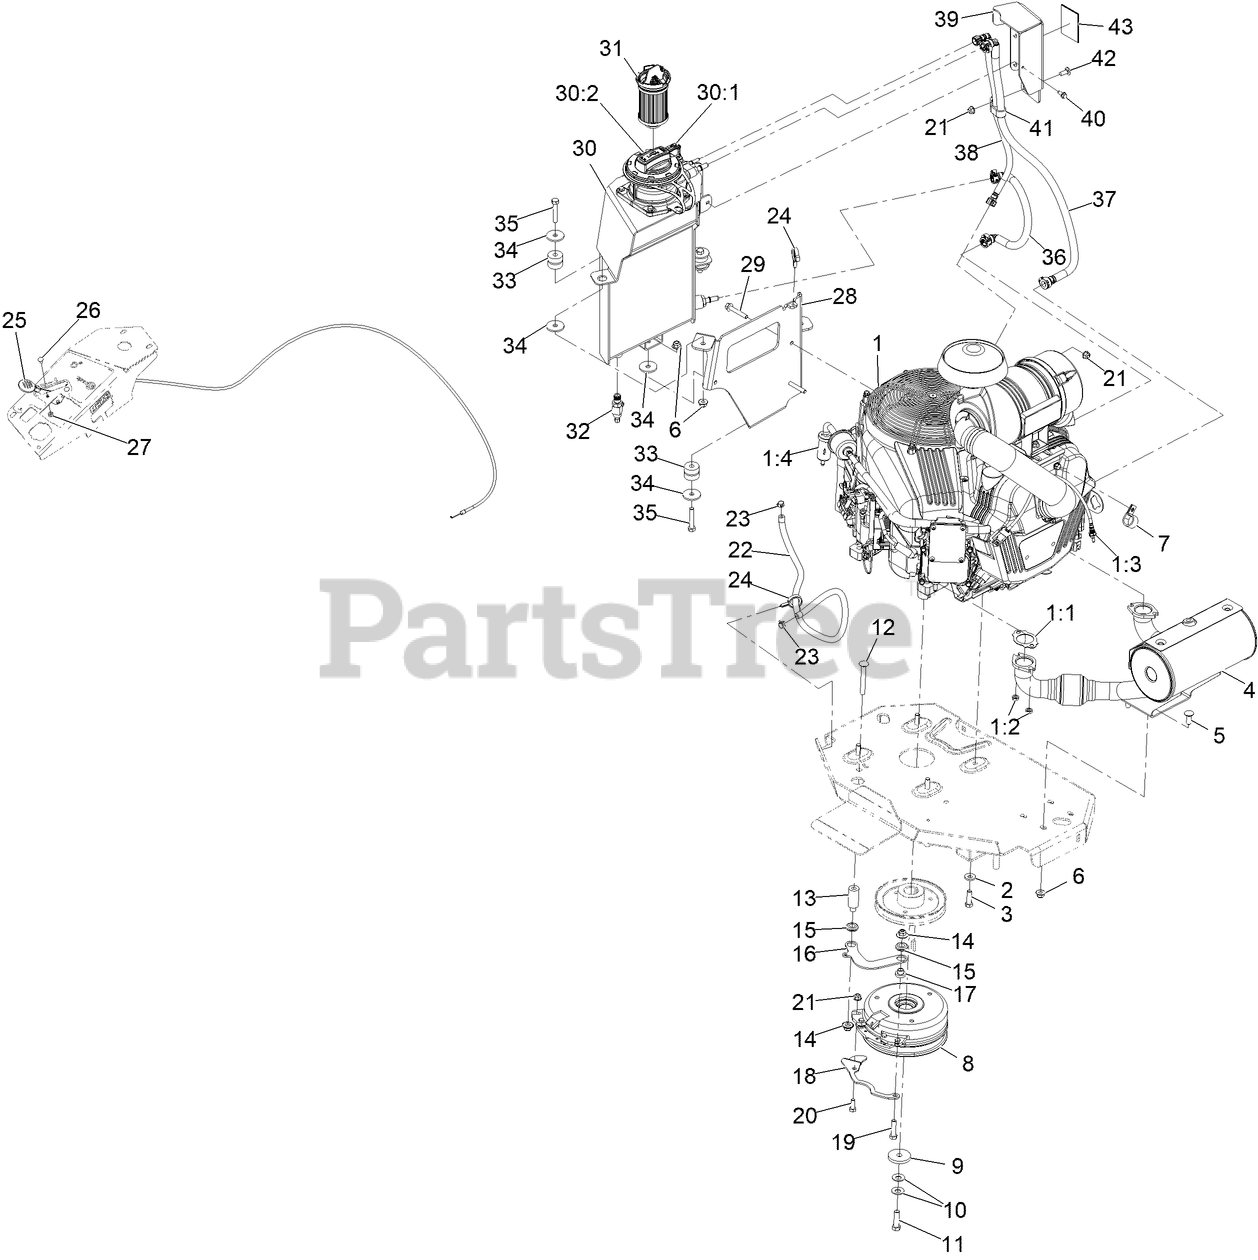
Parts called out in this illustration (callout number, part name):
1	Engine-Vanguard
1:1	GASKET-EXHAUST
1:2	NUT-HEX
1:3	SENSOR-O2
1:4	FILTER-FUEL
2	WASHER-BELLEVILLE
3	SCREW-HH
4	MUFFLER
5	SCREW-CARR
6	NUT-HF, NI
7	R-CLAMP
8	CLUTCH KIT
9	WASHER-CLUTCH
10	WASHER-SPRING
11	SCREW-HH 7/16-20 X 1 1/2 W/LOCTITE
12	SCREW-CARR
14	Nut-Nyloc 3/8-16 Flg
15	GROMMET-RUBBER
16	LINK-ANCHOR, CLUTCH
18	BELT-GUIDE
19	SCREW-HH
20	SCREW-HH
21	NUT-HF, NI
22	HOSE-FUEL
23	CLAMP-HOSE
24	CLAMP-HOSE
25	ASM,THROTTLE CABLE
26	BOLT-CARR
27	NUT-LOCK, NI
28	MOUNT-TANK, OIL
29	SCREW-HHF
30	RESERVOIR-OIL
30:1	OIL DIPSTICK ASM
30:2	OIL TANK CAP ASM
31	FILTER-OIL
32	VALVE-OIL DRAIN
33	ISOLATOR-TANK
35	SCREW-HH
36	HOSE-SUPPLY
37	HOSE-SCAVENGE
38	HOSE-VENT
39	GUARD-HOSE
40	SCREW-HWH
42	SCREW-CARR
43	DECAL-OIL GUARD
